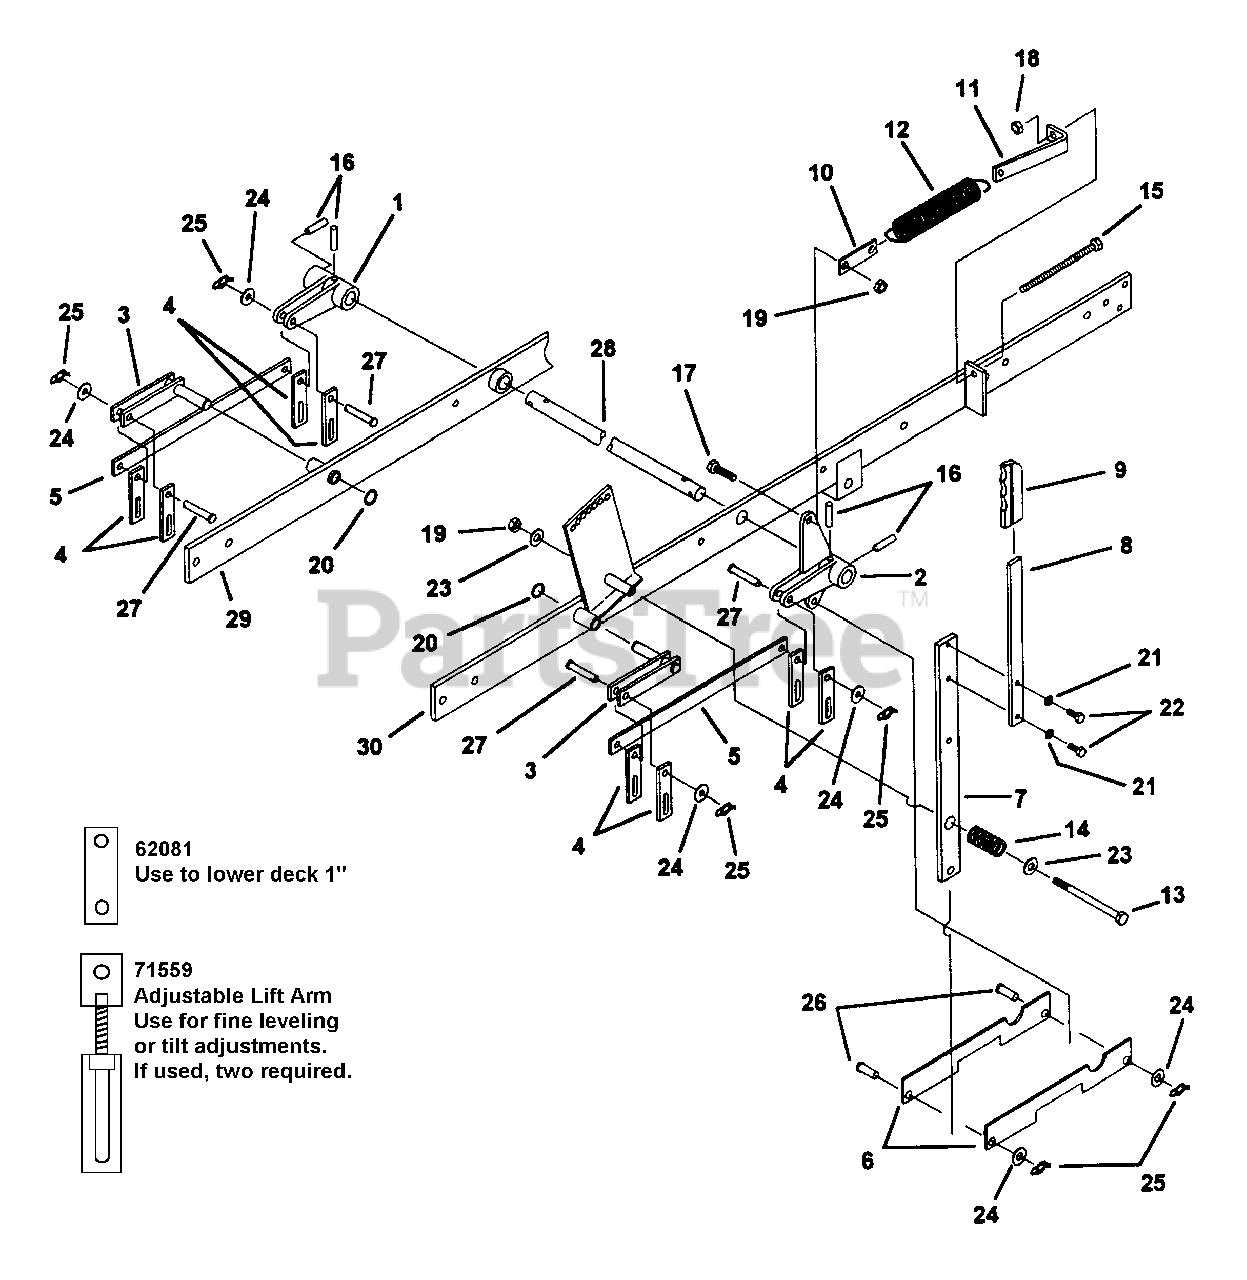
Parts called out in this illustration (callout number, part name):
1	LIFT SLEEVE WELDMENT, R.H.
2	LIFT SLEEVE WELDMENT, L.H
3	DECK HANGER WELDMENT
4	DECK HANGER BAR
5	BAR, CONNECTING
6	HANDLE LINK 41" DECK
7	DECK LIFT ARM WELDMENT 41" DECK
8	TOP, DECK HANDLE
9	GRIP, HANDLE
10	SPRING EXTENSION
11	SPRING TIGHTENER
12	SPRING
13	BOLT, 3/8-16 X 3" GR. 5
14	SPRING, COMPRESSION .975 O.D.
15	BOLT, 3/8-16 X 5" FULL THREAD
16	ROLL PIN, 5/16 X 1-1/4" HBK
17	BOLT, 3/8-16 X 1-1/4" GR. 5
18	NUT, 3/8-16 UNC-213
19	NUT, 3/8-16 NYLOC
20	RING, 5/8" External Retaining
21	LOCKWASHER, 1/4" SPLIT SPRING
22	BOLT, 1/4-20 X 3/4" GR. 5
23	WASHER, FLAT STD. 3/8"
24	WASHER, FLAT STD. 5/16"
25	COTTER RUE RING 5/16-3/8 PIN
26	CLEVIS PIN, 3/8 X 1"
27	CLEVIS PIN, 5/16 X 1-3/4"
28	LIFT BAR
29	FRAME SIDE WELDMENT, R.H.
30	FRAME SIDE WELDMENT, L.H.
62081	BAR, DECK HANGER
71559	ARM, LIFT, ADJUSTABLE
